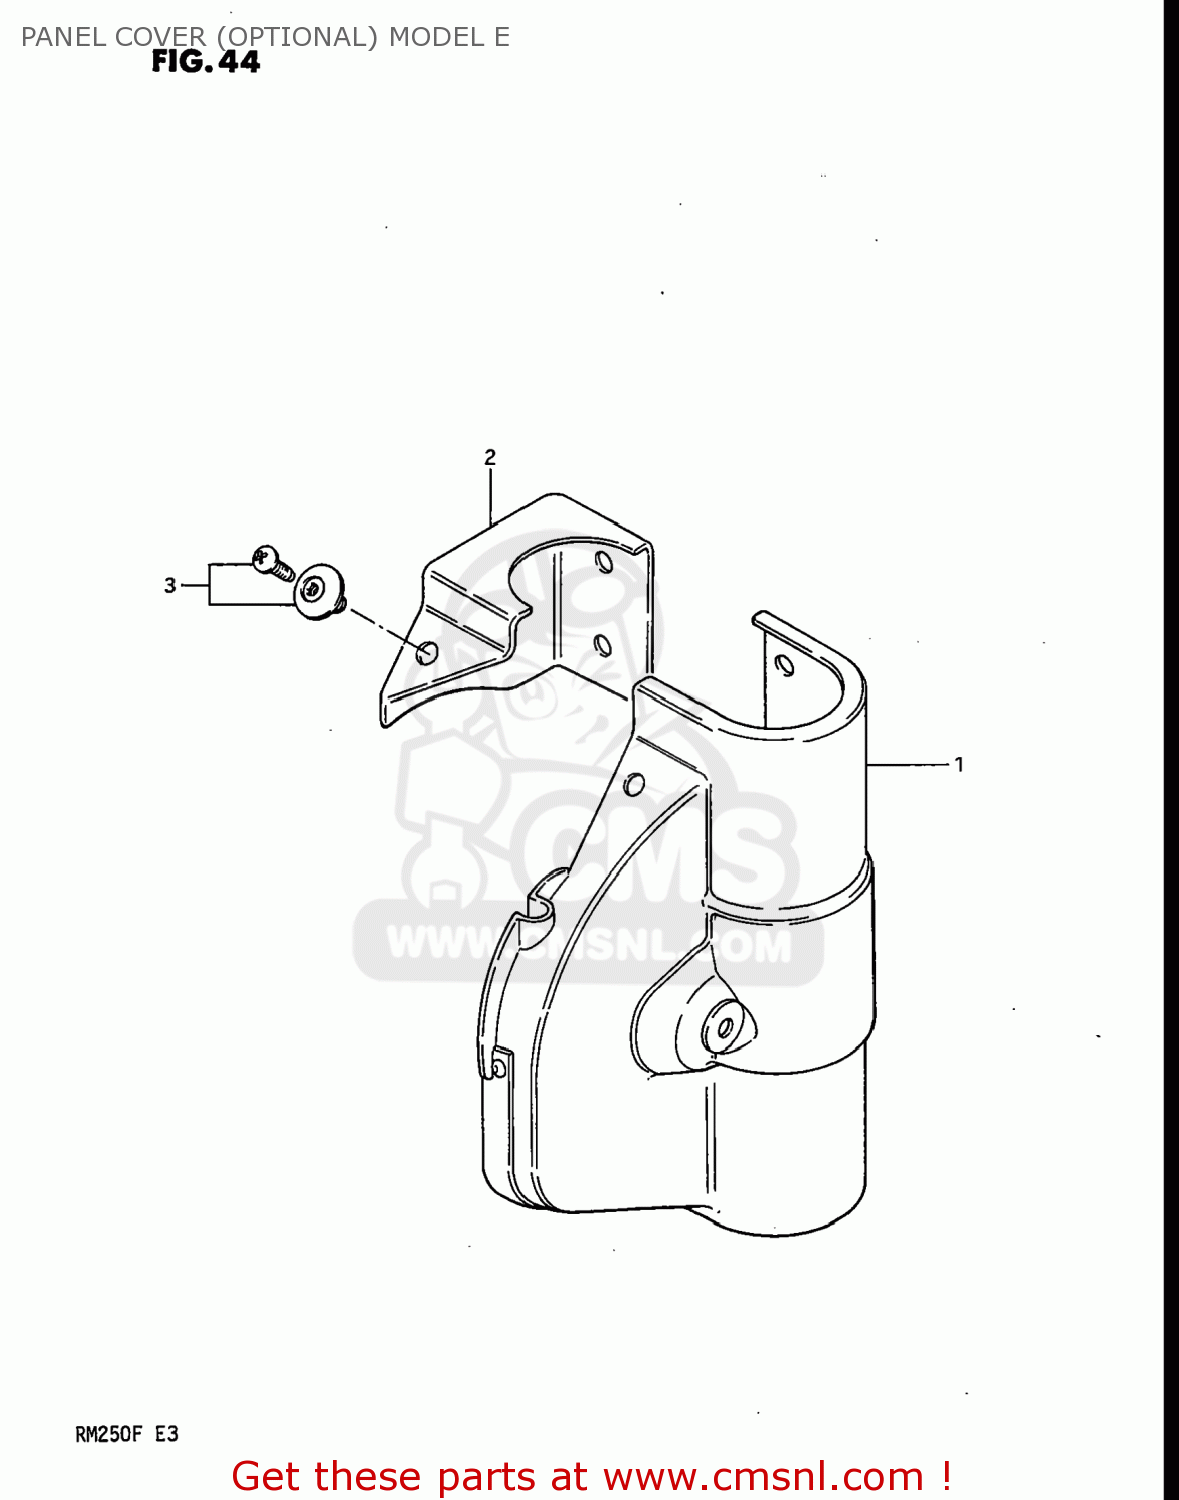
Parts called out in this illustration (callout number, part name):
1	COVER,FRONT HUB PANEL
2	CAP
3	CLIP(BLACK)
